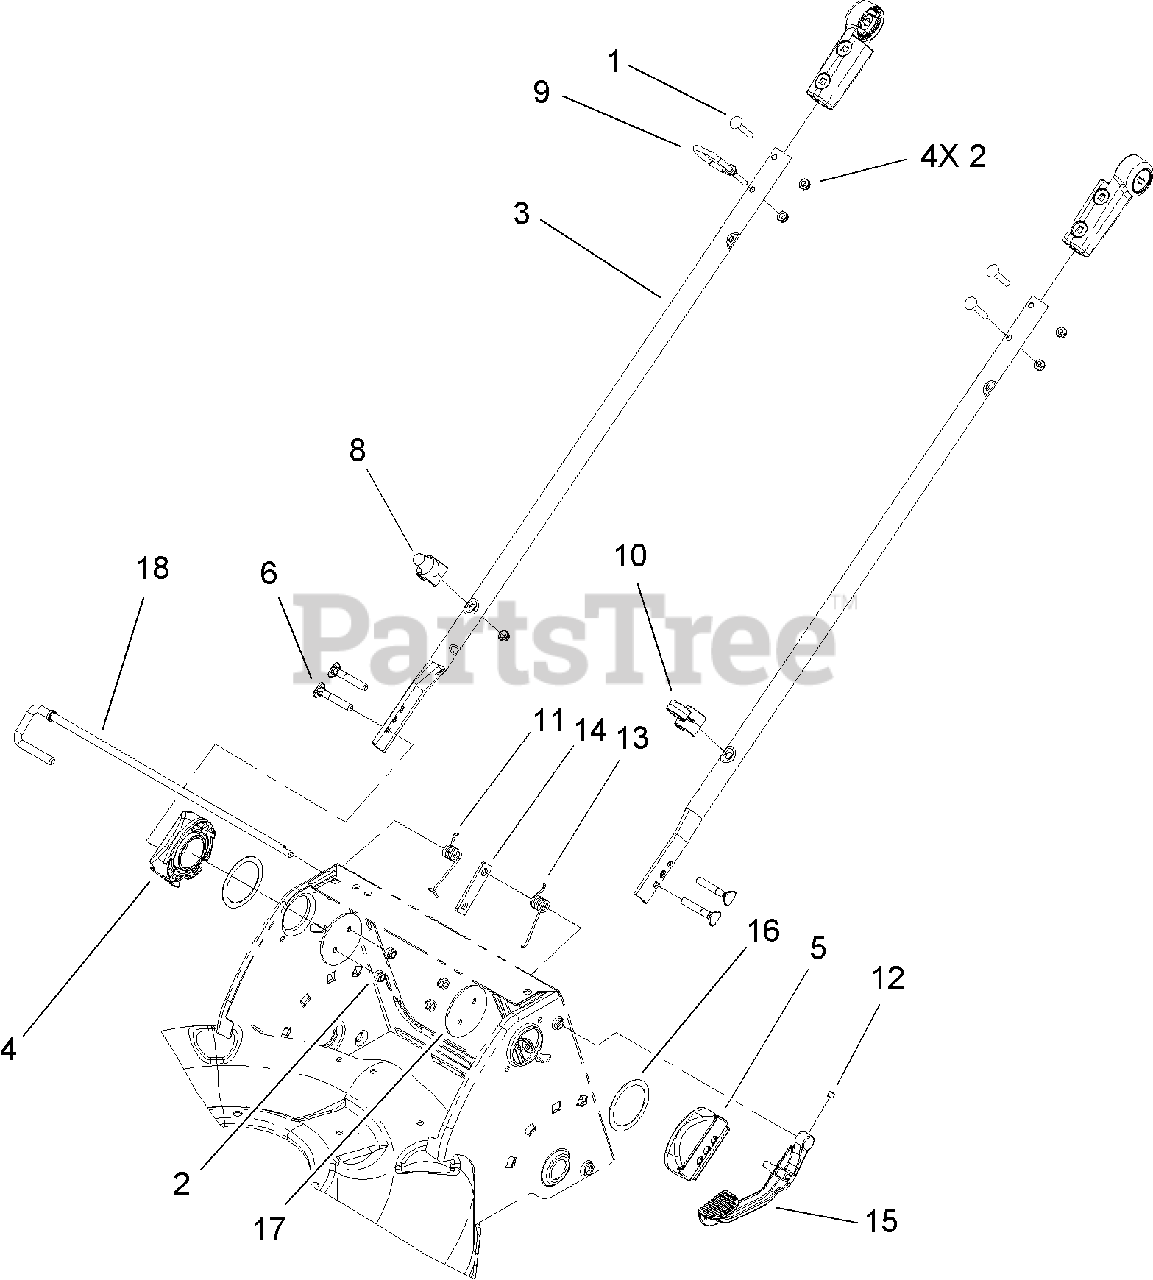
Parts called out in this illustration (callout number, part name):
1	SCREW-CARR
2	NUT-LOCK, NI
4	MOUNT-HANDLE, RH
5	MOUNT-HANDLE, LH
8	GUIDE-ROPE, LOWER
9	GUIDE-ROPE, UPPER
10	Guide-Cable
11	SPRING-TORSION, LH
12	SCREW-SET
13	SPRING-TORSION, RH
14	PLATE-LOCK, HANDLE
15	LEVER-RELEASE
16	WASHER-NYLON
18	ROD-RELEASE
